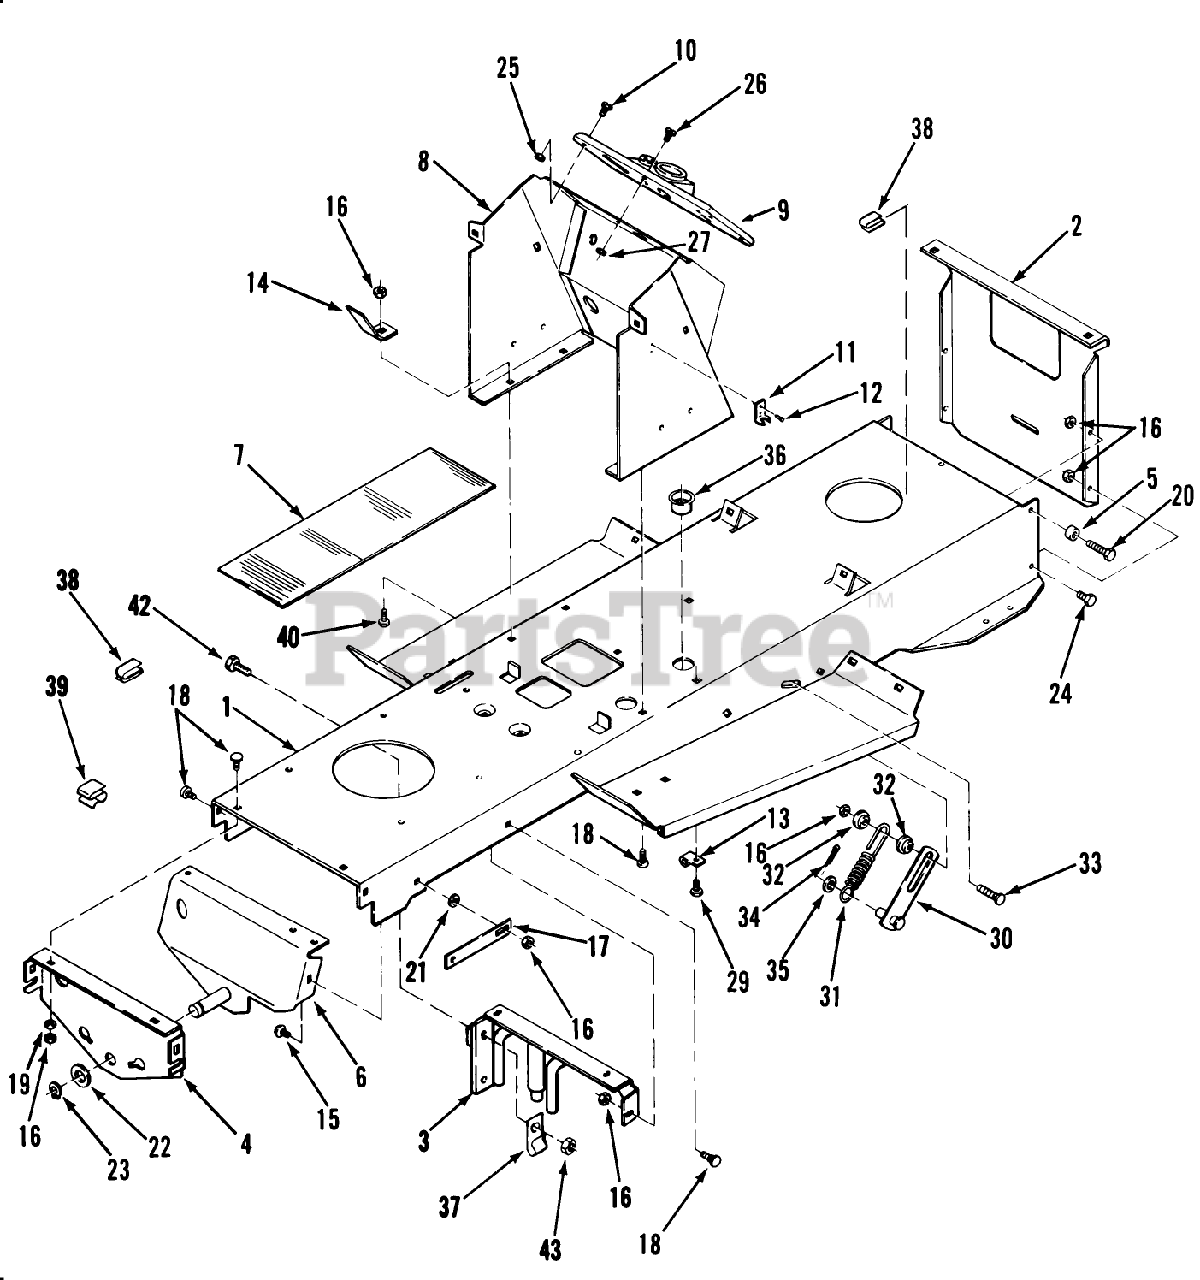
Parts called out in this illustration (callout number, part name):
2	PLATE DRAWBAR
4	PLATE SUPT - AXLE *R
5	BEARING CAM ROLLER
7	PAD-FOOTREST
13	J-CLIP
17	STRAP *R
19	WASHER 5/16 SAE
22	WASHER
22	WASHER-SHIM
31	SPRING
35	WASHER-FLAT
36	BUSHING-NYLON 1.093
37	CLIP
39	CLIP-CABLE
